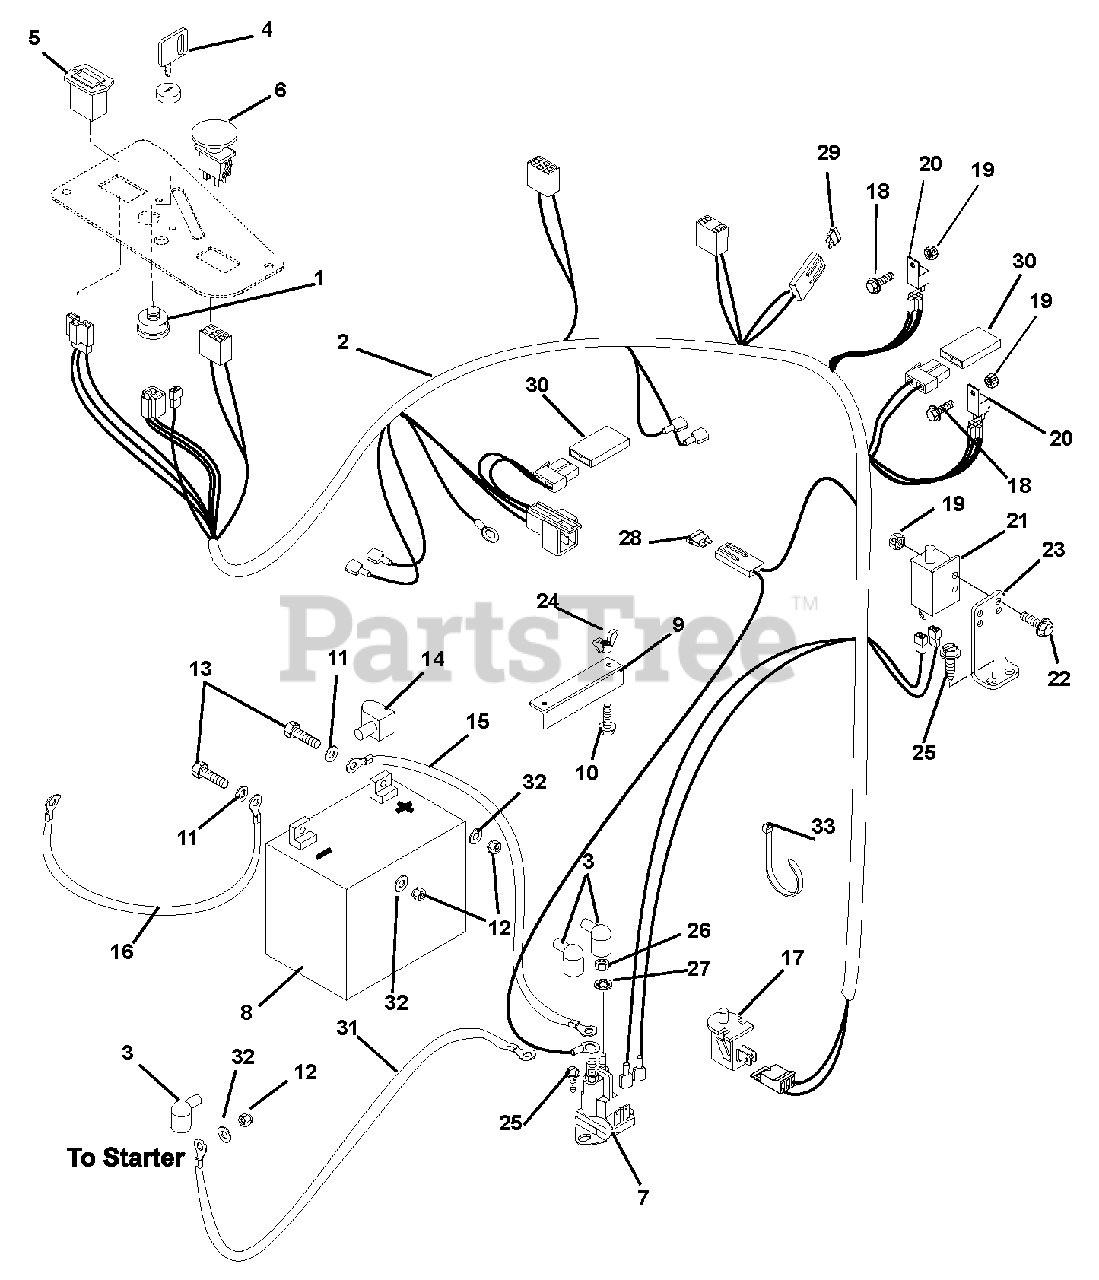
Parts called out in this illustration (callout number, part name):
1	Key Switch
2	Harness, Wiring IZ/CZ 6-Pin
3	Boot, Eyelet Terminal
4	Key with Shield
5	Hour Meter – Digital
6	Switch, Clutch With Retainer Ring
7	Solenoid
9	Hold Down
10	Bolt, Round Head Square Neck .25-20 x 7.50
11	Washer, Flat Steel .281 x .620 x .065
12	Nut, Hex .25-20
13	Bolt, Hex .25-20 x .75 Grade 5
14	Insulator
15	Cable, Positive Battery 9.00"
16	Cable, Negative Battery
17	Switch, Snap Mounting (N.O.)
18	Screw, Machine 10-24 x .50 Hex Washer Head
19	Nut, Locking Nylon 10-24 With Insert
20	Relay (Included with Harness)
21	Switch, Single Pole
22	Screw, Machine 10-24 x .75 Hex Washer Head
23	Mount, Brake Switch
24	Nut, Locking Wing .25-20
25	Screw, Tapping .25-20 x .50 Hex Washer Head
26	Nut, Jam .31-24
27	Washer, Locking .31 x .078 Regular
28	Fuse, 25 Amp (Included with Harness)
29	Fuse, 20 Amp
30	Diode, Connector Shell
31	Cable, Starter
32	Washer, Lock .25 x .062
33	Tie, Cable LG 5.50
